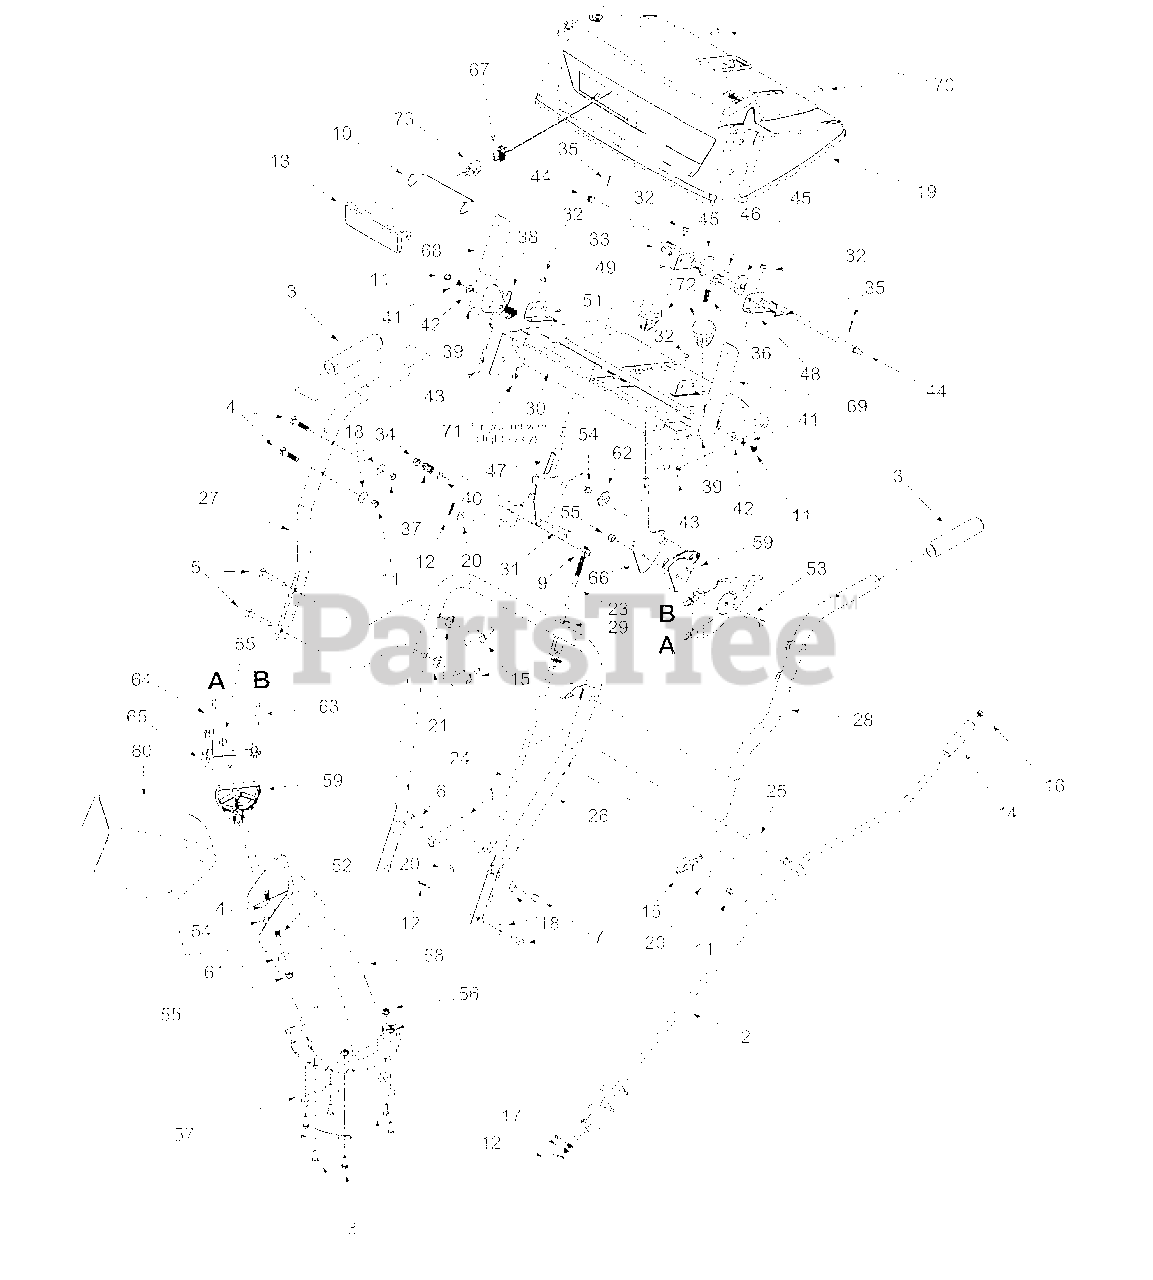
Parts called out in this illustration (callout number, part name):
2	Chute Crank Ass'y
3	Handle Grip
4	Carriage Bolt, 5/16-18 x 1.5
5	Carriage Bolt, 5/16-18 x 2.25
6	Self Tapping Screw, 1/4-20 x 1
7	Hex Cap Screw, 5/16-18 x .75
8	Hex Cap Screw, 1/4-20 x .75
9	Ferrule, 5/16-18 x .312
10	Headlamp Retainer
11	Hex Nut, 5/16-18
12	Internal Cotter Pin
13	Lens Assembly / Lamp Housing
14	Chute Crank Knob
15	Wing Knob, 5/16-18
16	Push Cap, 3/8
17	Flat Washer, .375 x .738 x .063
18	Bell Washer, .34 x .872
19	Handle Panel
20	Flat Washer, .344 x .688 x .065
21	Saddle Washer, .32 x .93
23	Upper Shift Rod
24	Lower Shift Rod
29	Shift Rod Connector
31	Hex Cap Screw, 3/8-24 x 1.5
32	Self Tapping Screw, 1/4-20 x.5
33	Clevis Pin
34	Jam Nut, 3/8-24
35	Cotter Pin, .072 x 1.0
36	Compression Spring, .36 x 1.0
37	Comp. Spring, .39 x .6 x .88
38	Torsion Spring, .44 x.8
39	Rubber Bumper
40	Bell Washer, .401 x .87 x .063
41	Lock Washer, 5/16
42	Special Washer,.35 x .72 x .13
43	Cable "Z" Fitting
45	Cam Handle Lock
46	Handle Lock Pawl
52	Carriage Bolt, 5/16-18 x .75
53	Hex Cap Screw, 5/6-18 x 1.5
54	Screw, 1/4-14 x .625
55	Hex Lock Nut, 5/16-18
56	Hex Flange Lock Nut, 1/4-20
57	Lower Chute Flange Keeper
58	Lower Chute
59	Chute Tilt Cable Guide
60	Upper Chute
61	Washer, 5/16
62	Special Washer, .28 x 1.2 x .06
63	Chute Deflector Control Cable
64	Chute Deflector Cable w/ Clip
67	Halogen Light Harness
68	RH Engagement Handle Ass'y
69	LH Engagement Handle Ass'y
70	Special Screw, #10-16 x .625
71	Hex Sams Nut, 1/4-20
72	Plastic Knob
73	Halogen Lamp, 12-volt, 27 Watt
